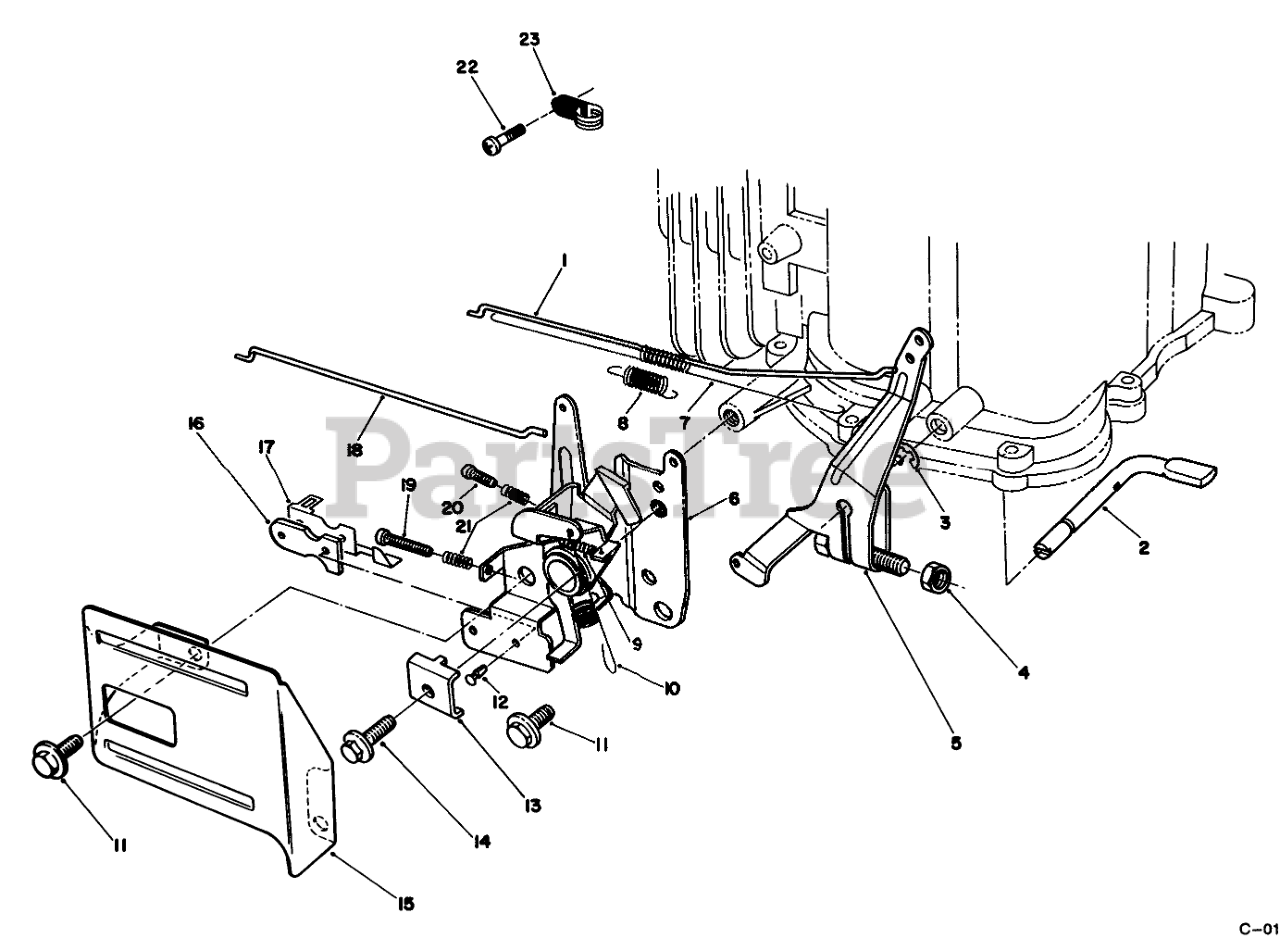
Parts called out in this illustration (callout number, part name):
1	Rod-Carburetor
2	SHAFT
3	E-RING
4	Nut
5	ARM ASM
6	THROTTLE
7	SPRING
8	SPRING
9	SPRING
10	SPRING
12	RIVET
13	CLAMP-CABLE
15	THROTTLE GUARD
16	INSULATOR-KILL SWITCH
17	TERMINAL-KILL SWITCH
18	Rod-Choke
19	SCREW
20	SCREW
21	SPRING
22	SCREW
23	Clamp
